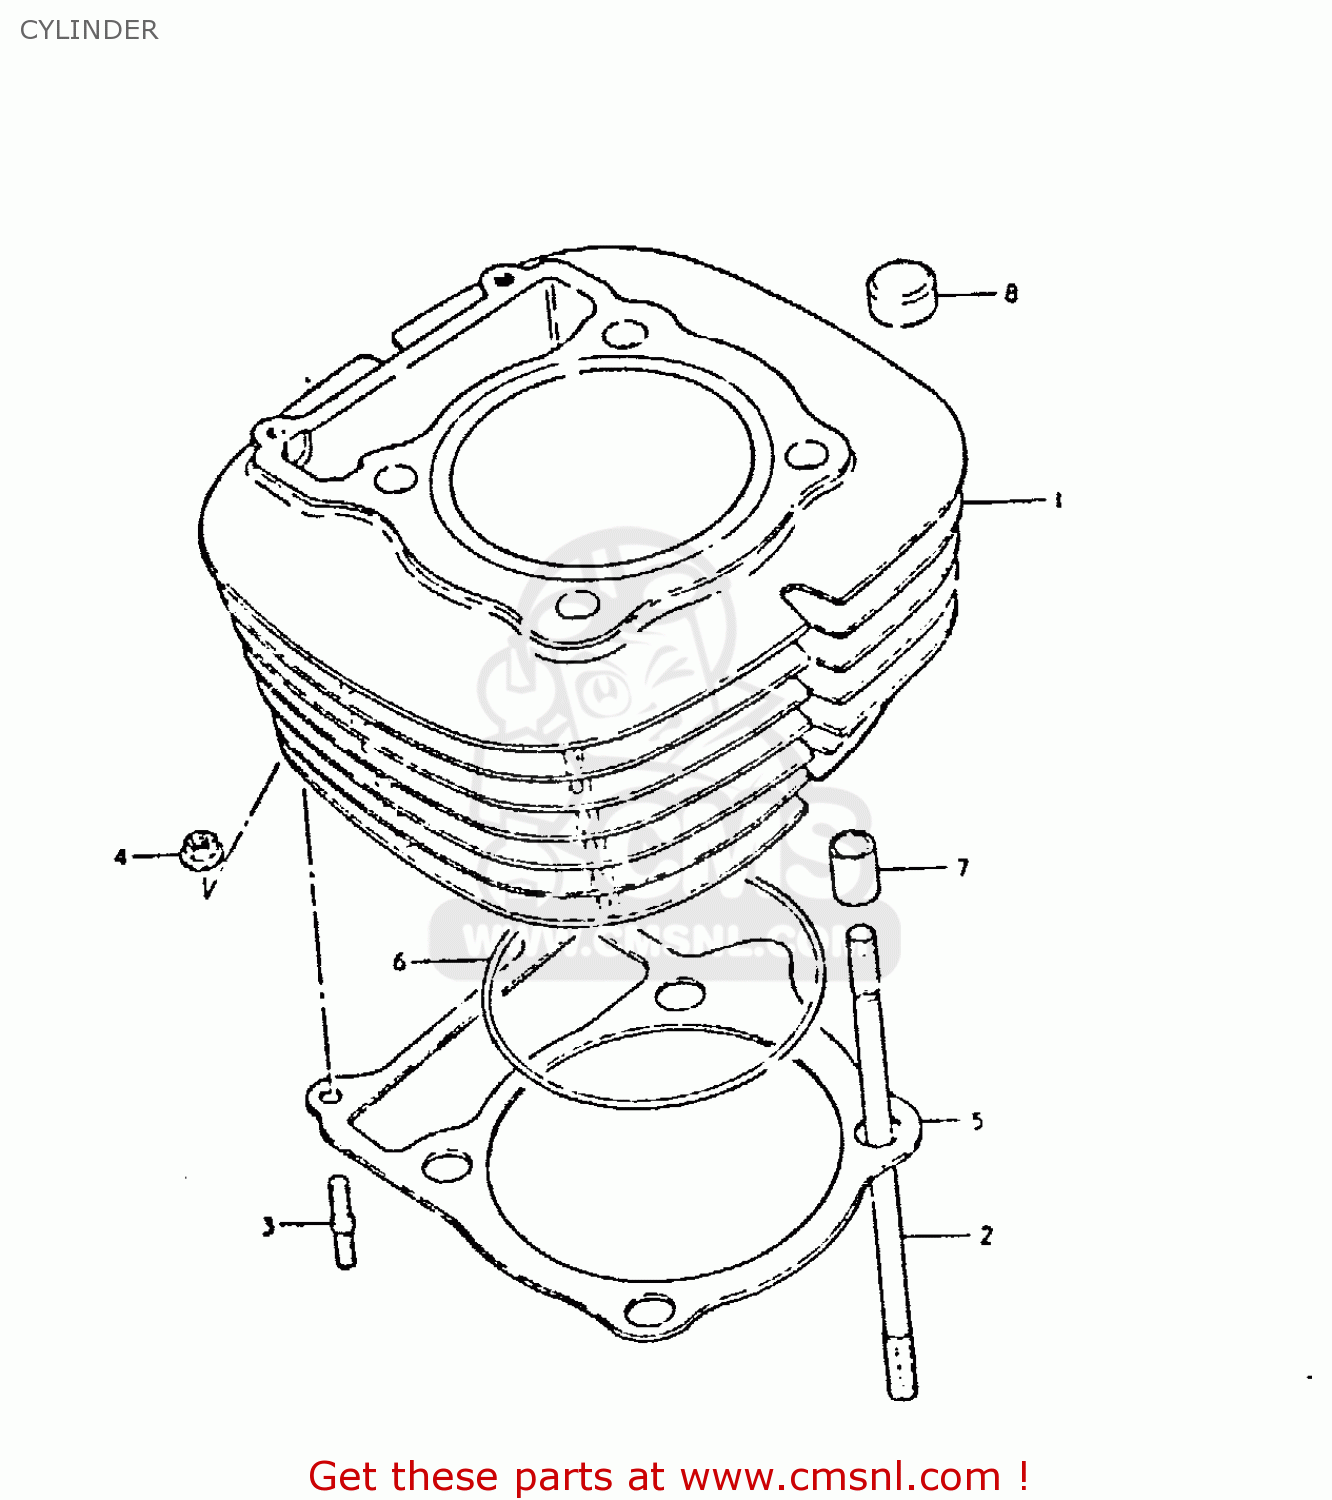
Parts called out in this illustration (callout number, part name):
1	CYLINDER
2	STUD
3	STUD 6X20
4	NUT
5	GASKET,CYLINDER (MCA)
6	O RING(D:2,ID:87)
7	PIN
8	PAD,CYLINDER HEAD
